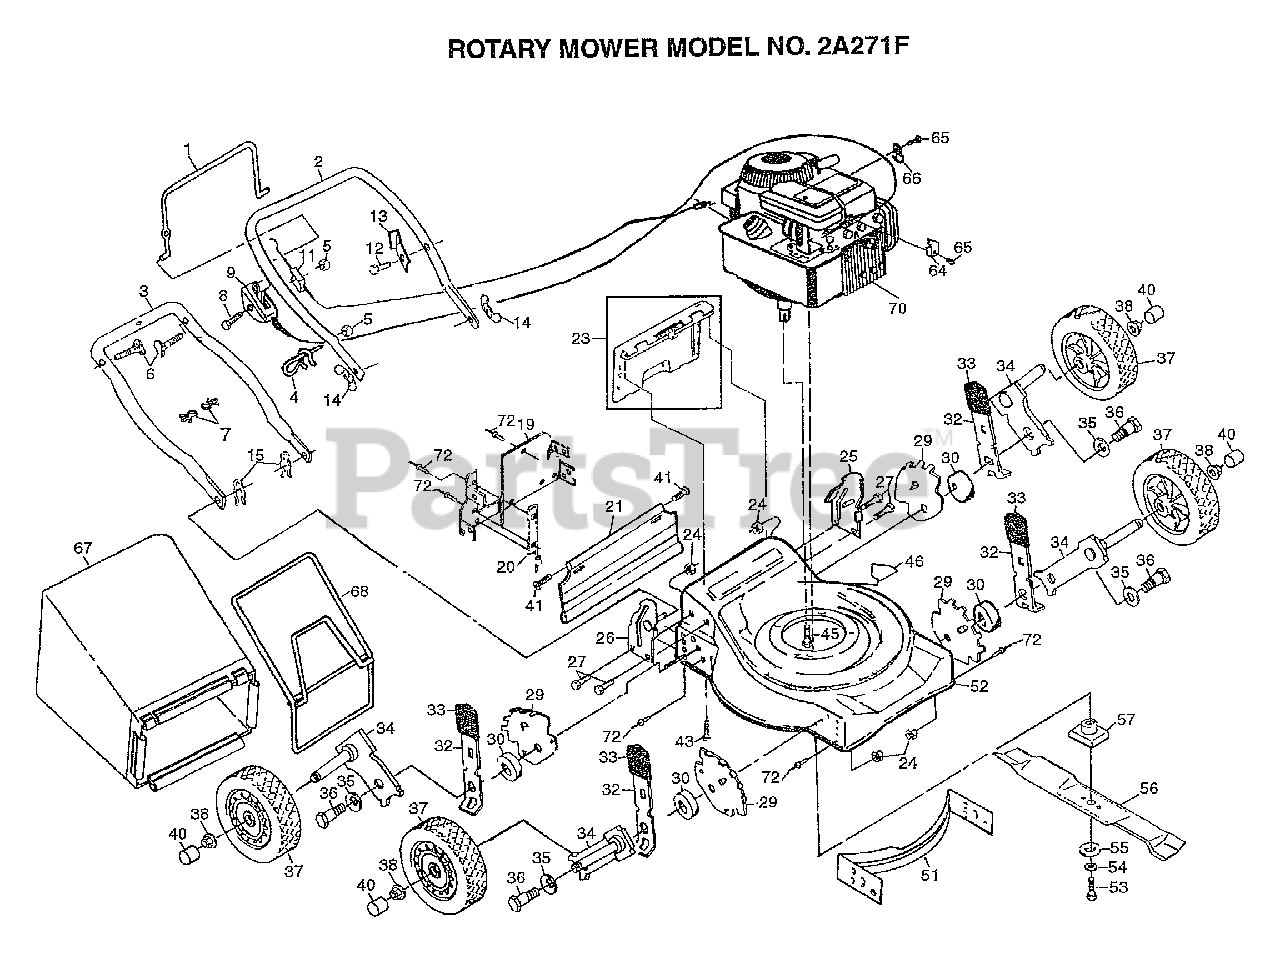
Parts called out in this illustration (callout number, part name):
1	CONTROL BAR
3	HANDLE.LWR.DLX.20
4	ROPE GUIDE
6	BOLT.HANDLE.LM
8	SCREW.HXHD.WASH.
9	CONTROL THROTTLE
11	"CABLE,ENG ZONE CO"
12	TAPPING SCREW
13	"BRKT,UPSTOP"
14	"NUT,WING PM"
15	HAIRPIN COTTER
19	PLATE.BACK.20RD
21	SKIRT.PUSH.20RD
23	KIT.DOOR.RR.20STL
24	LOCKNUT PM
25	BRACKET.HDL.LH.
26	BRACKET.HDL.RH.
27	SCREW.HXWS.5/16
29	BRACKET.WHL.ADJ.9
30	SPACER.HEIGHT.ADJ
32	SPRING SELECTOR
33	KNOB PM
34	ARM.AXLE.ASM.BZP.
35	"WASHER, BELLEVIL."
36	BOLT SHLD 3/8-16
37	WHEEL.ASM
38	HEX FLANGE LOCKNT
40	HUB CAP-PLASTIC
41	HINGE SCREW
43	SCREW
45	BOLT.ENG.3/8-16
46	DECAL HYT
53	SCREW
54	LOCKWASHER
55	"WASHER,HARDEN"
57	BLADE ADAPTOR
64	CABLE CLAMP
65	SCREW PM
66	GUIDE CLIP PM
67	GRASSBAG.250B1.BL
68	FRAME.CATCHER.2.5
72	BLIND RIVET
